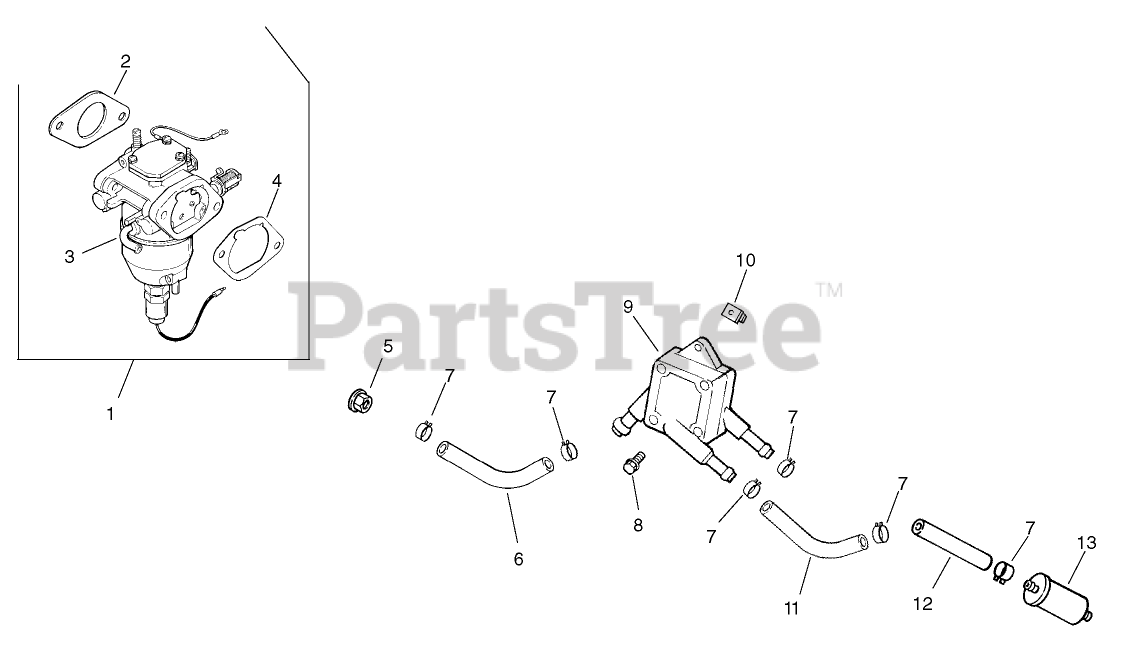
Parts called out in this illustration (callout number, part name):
1	Kit, carburetor w/gaskets (Includes 2-4)
2	Gasket-carburetor
3	Carburetor assembly (For information only not available separately)(Service with kits 24 757 36-S and 24 757 38-S)
4	GASKET-BASE, AIR CLEANER
5	NUT-FLANGE (M6X1.0)
6	Line, fuel 12"
7	CLAMP-HOSE, SPRING (1/2)
8	SCREW-TAP (M6X1.7X18)
9	PUMP-FUEL
10	Nut-Plastic
11	Line, fuel 10-1/2
12	Line-Fuel (9.5)
13	Filter, fuel
